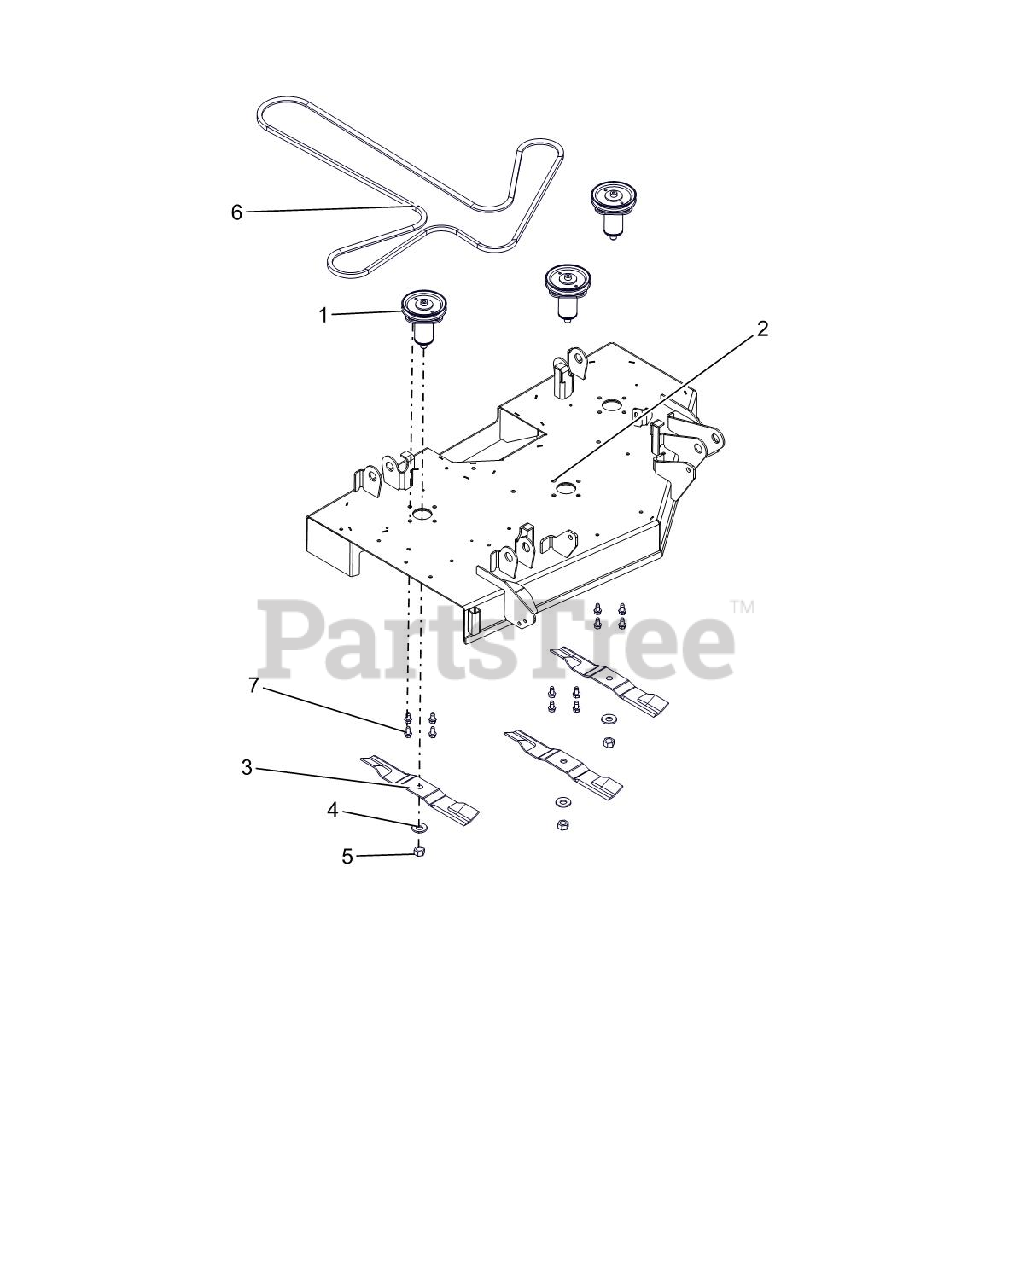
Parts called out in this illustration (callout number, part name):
1	KIT, DECK SPINDLE ASM-IKON-ZTX
2	KIT, 42" GRAVELY DECK W/DECALS
3	BLADE, MOWER 15.00"
4	WSHR-BLVL .669X1.535X.138
5	NUT-HEX .62-18 YWZC
6	V-BELT, 4L-WRAPPED
7	SCR-TAP .38-16X.75 HWH TR YWZ
